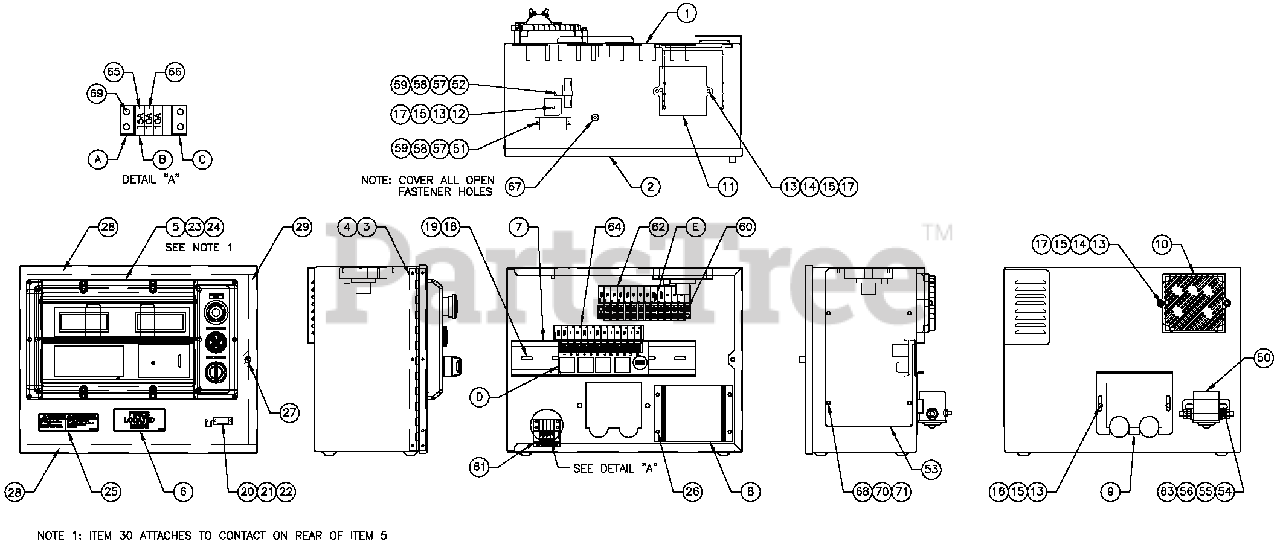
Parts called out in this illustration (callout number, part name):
1	ENCLH/G CONTROL PANEL
2	COVER CONTROL PANEL
3	HINGE CONTINUOUS H PANEL
4	RIVET POP .125X .275SS
5	ASSY PROGRAMMED H-100
6	DECAL FUSES LOCATED INSIDE
7	RAIL SNAPTRACK PCB HOLDER BULK (12" LG)
8	ASSY PCB 2AMP 12V UL BATT CHGR
9	PLATE HARNESS CLAMP
10	ASSY PCB PWR AVRW/AMP HEADER
11	ASSY PCB BOSCH GOV DRIVER
12	DIO BRIDGE 25A 600V
13	WASHER LOCK M5
14	SCREW PPHM M5-0.8X 30SS
15	WASHER FLAT M5
16	SCREW HHPM M5 0.8X12
17	NUT HEX M5 0.8 G8 YEL CHR
18	WASHER FLAT M4
19	SCREW PHTT M4-0.7 X 10ZYC
20	CONN DUST CAP W/CHAIN DB9
21	WASHER FLAT M3.5
22	SCREW PHTT M3.5 0.6 X 10
23	SCREW PPHM M4-0.7 X 8 BLXOX
24	WASHER LOCK #8 M4
25	DECAL WRNB ATT CHRG 12/24V BI
26	SCREW PHTT M4-0.7 X 12 ZYC
27	M5 0.8 CAPTIVE PANEL KNLD HD
28	SEAL COVER 3.18 X 12.7 X 382
29	SEAL COVER 3.18 X 12.7 X 283
50	RELAY CONTACTOR 12VDC
53	COVER CONTROL PANEL SIDE
54	SCREW HHC 1/4-20X3/4G5
55	WASHER FLAT M6-1/4
56	WASHER LOCK M6-1/4
57	WASHER LOCK M3
58	NUT HEX M3-0.5G8 YEL CHR
59	WASHER FLAT M3
60	SCREW PHTT #6-32 X 5/8ZYC
61	DECAL CPL CONTROL PANEL FUSES
62	DECAL CPL 5.4/6.8L TB3
63	NUT HEX 1/4-20 STEEL
64	DECAL CPL 5.4/6.8L RELAY BOARD
65	FUSE ATO TYPE 15 AMP (BLUE)
66	FUSE ATO TYPE 10 AMP (RED)
67	SEAL WEATHER.45"DIA
68	SCREW PPHM M5-0.8 X 12ZNC
69	SCREW PHTT#6-32 X 3/8ZYC
70	WASHER FLAT M5
71	WASHER LOCK M5
A	ADPTR RH SIDE WICKMANN 178.6191
B	HOLDERFUSE WICKMANN 178.6150
C	ADPTR LH SIDE WICKMANN 178.6192
D	ASSYPCB G-PANEL RELAY 12VDC
E	BLOCK TERM 20A 12X 6 X 1100V
